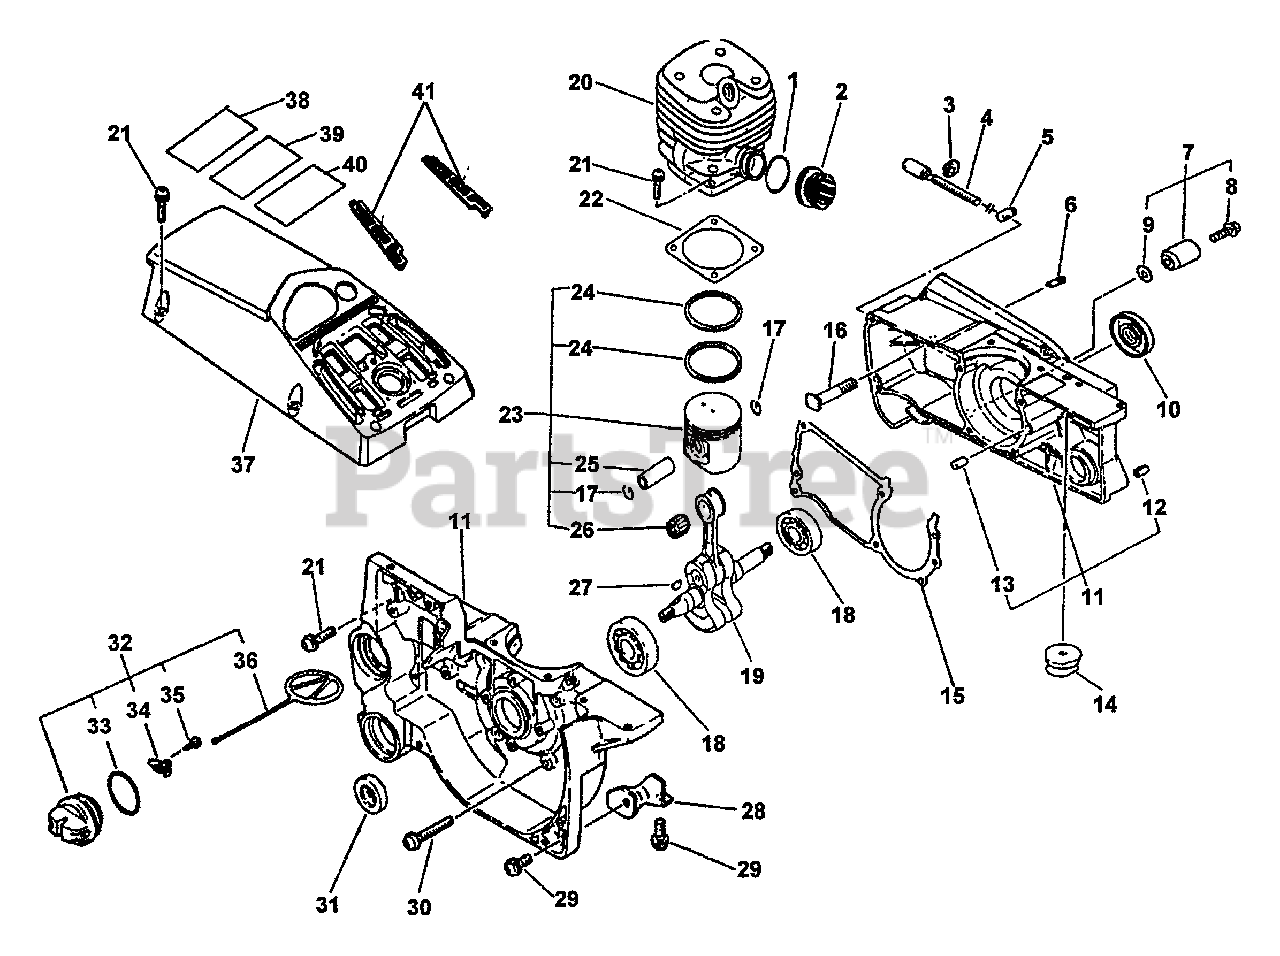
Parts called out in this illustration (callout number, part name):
2	ADAPTOR, INTAKE
4	SCREW, ADJUSTER
5	TENSIONER, CHAIN
6	VENT ASSY
7	CHAIN CATCHER KIT
8	SCREW 5×20
9	WASHER, FLAT 5.5×10×0.8
10	SEAL, OIL
11	CRANKCASE KIT
12	PIN, SPRING 5×10
13	PIN, LOCATING 5×10
15	GASKET, CRANKCASE
16	STUD, GUIDE BAR 8
17	RING, SNAP
18	BEARING, BALL 6202
19	CRANKSHAFT
20	CYLINDER KIT
21	BOLT 5×20
22	GASKET, CYLINDER
23	PISTON KIT
24	RING, PISTON
25	PIN, PISTON
26	BEARING, NEEDLE
27	KEY, WOODRUFF
29	SCREW 5×14
30	BOLT M5×35
31	SEAL, OIL
32	CAP ASSY
34	RETAINER, CONNECTOR
35	SCREW, TAPPING 3×8
36	CONNECTOR, CAP L= 60 MM
37	COVER, ENGINE
38	LABEL, CAUTION
39	LABEL - KICK BACK
40	LABEL - CAUTION
41	FILTER KIT
